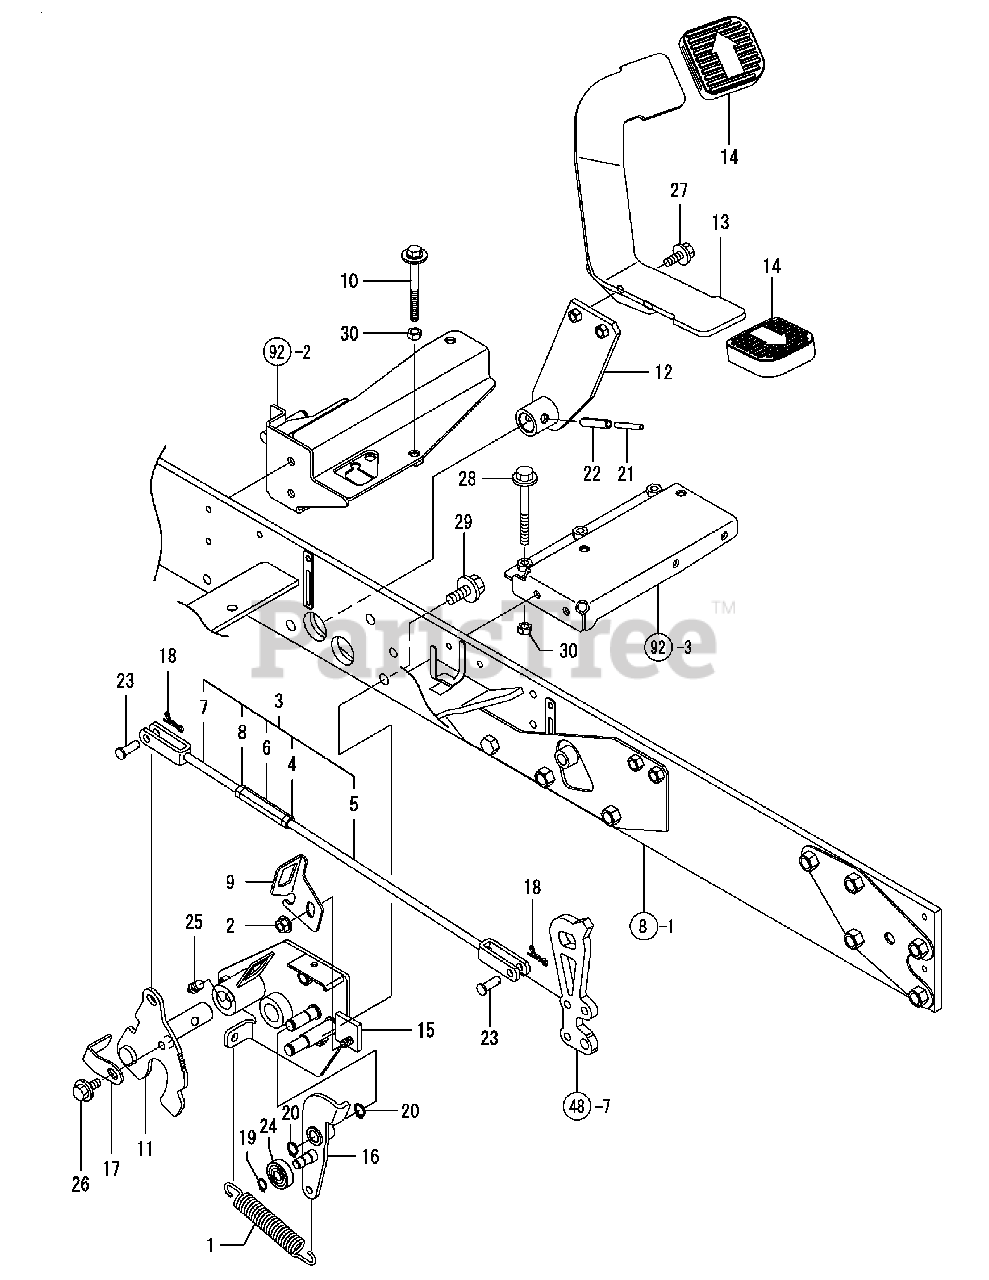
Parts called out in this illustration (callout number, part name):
1	SPRING, RETURN
2	NUT W/WASHER 8
4	NUT W/WASHER 8
5	ROD B CMP, HST
6	TURNBUCKLE 8X60
10	BOLT, HST PEDAL
12	PEDAL, ARM CMP
13	PEDAL , HST CMP
15	FULCRUM, PEDAL CMP
16	ARM, SWITCH CMP
18	PIN 8, COME-OFF SNAP
21	SPRING PIN 5X40
22	SPRING PIN 8X40
25	NIPPLE PT1/8, GREASE
26	BOLT M 8X 16 PLATED
27	BOLT M 8X 20 PLATED
28	BOLT M 8X 80 PLATED
29	BOLT M10X 25 PLATED
